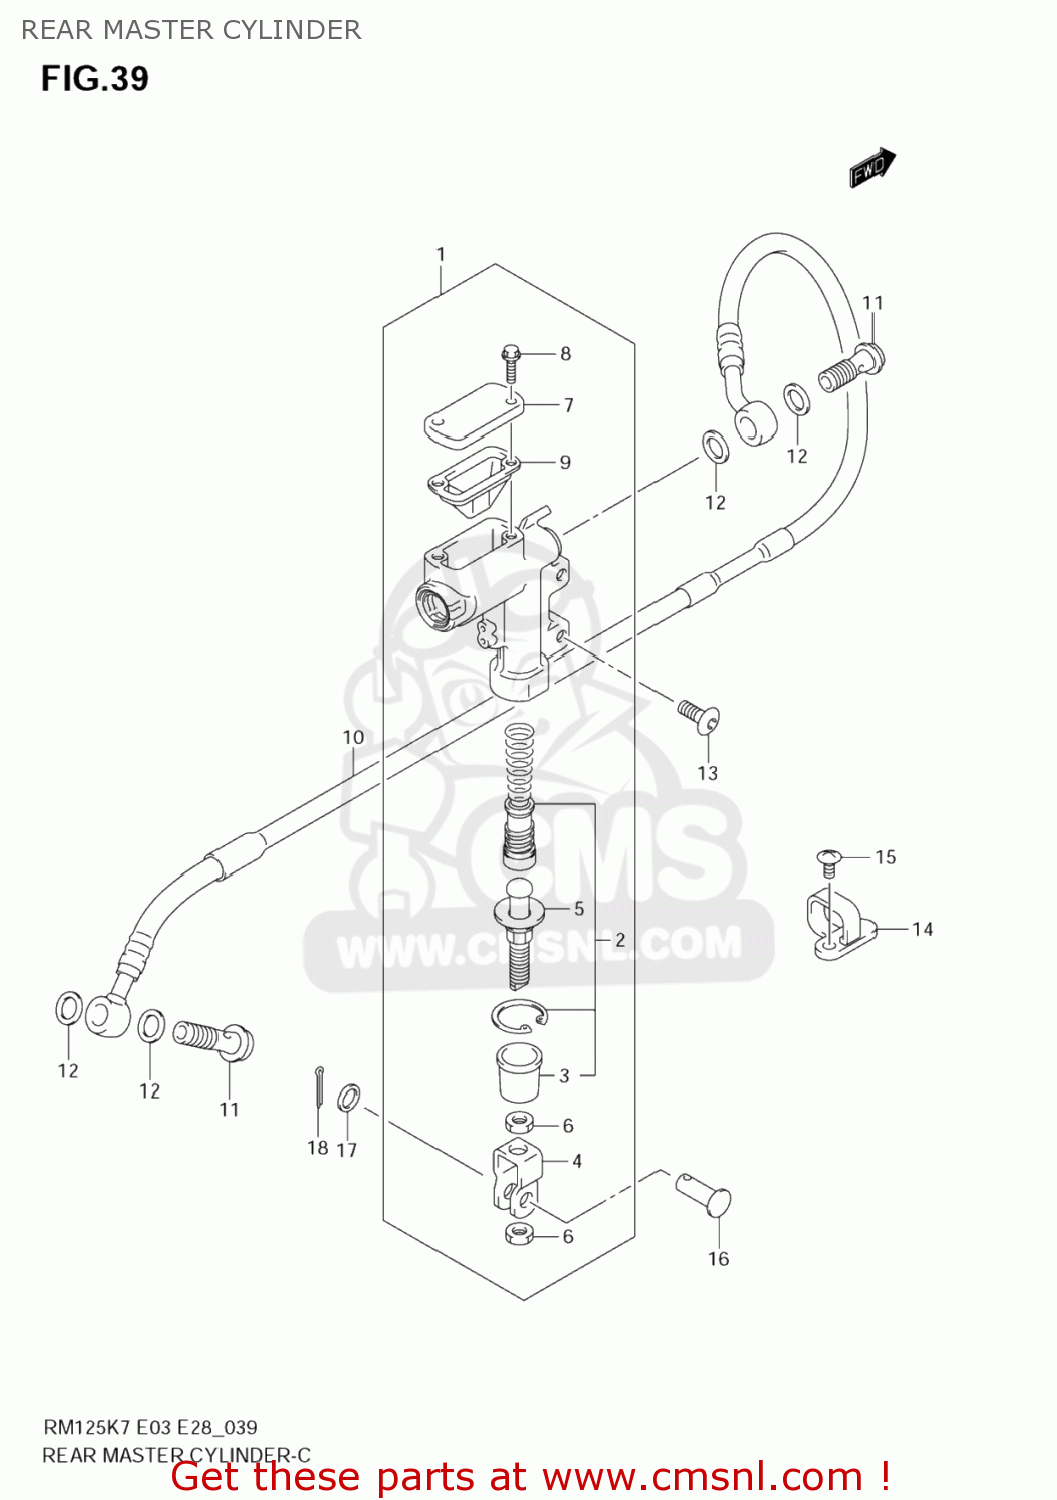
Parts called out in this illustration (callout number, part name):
1	CYLINDER SET,RR MASTER
2	PISTON/CUP SET
3	BOOT
4	YOKE
5	ROD,PUSH
6	NUT
7	CAP
8	SCREW
9	DIAPHRAGM
10	HOSE COMP,REAR
11	BOLT UNION
12	WASHER(10X15X1.5)
13	SCREW(6X16)
14	GUIDE,RR BRAKE
15	SCREW
16	PIN(8X20)
17	WASHER (8.5X14X1.6)
18	PIN
